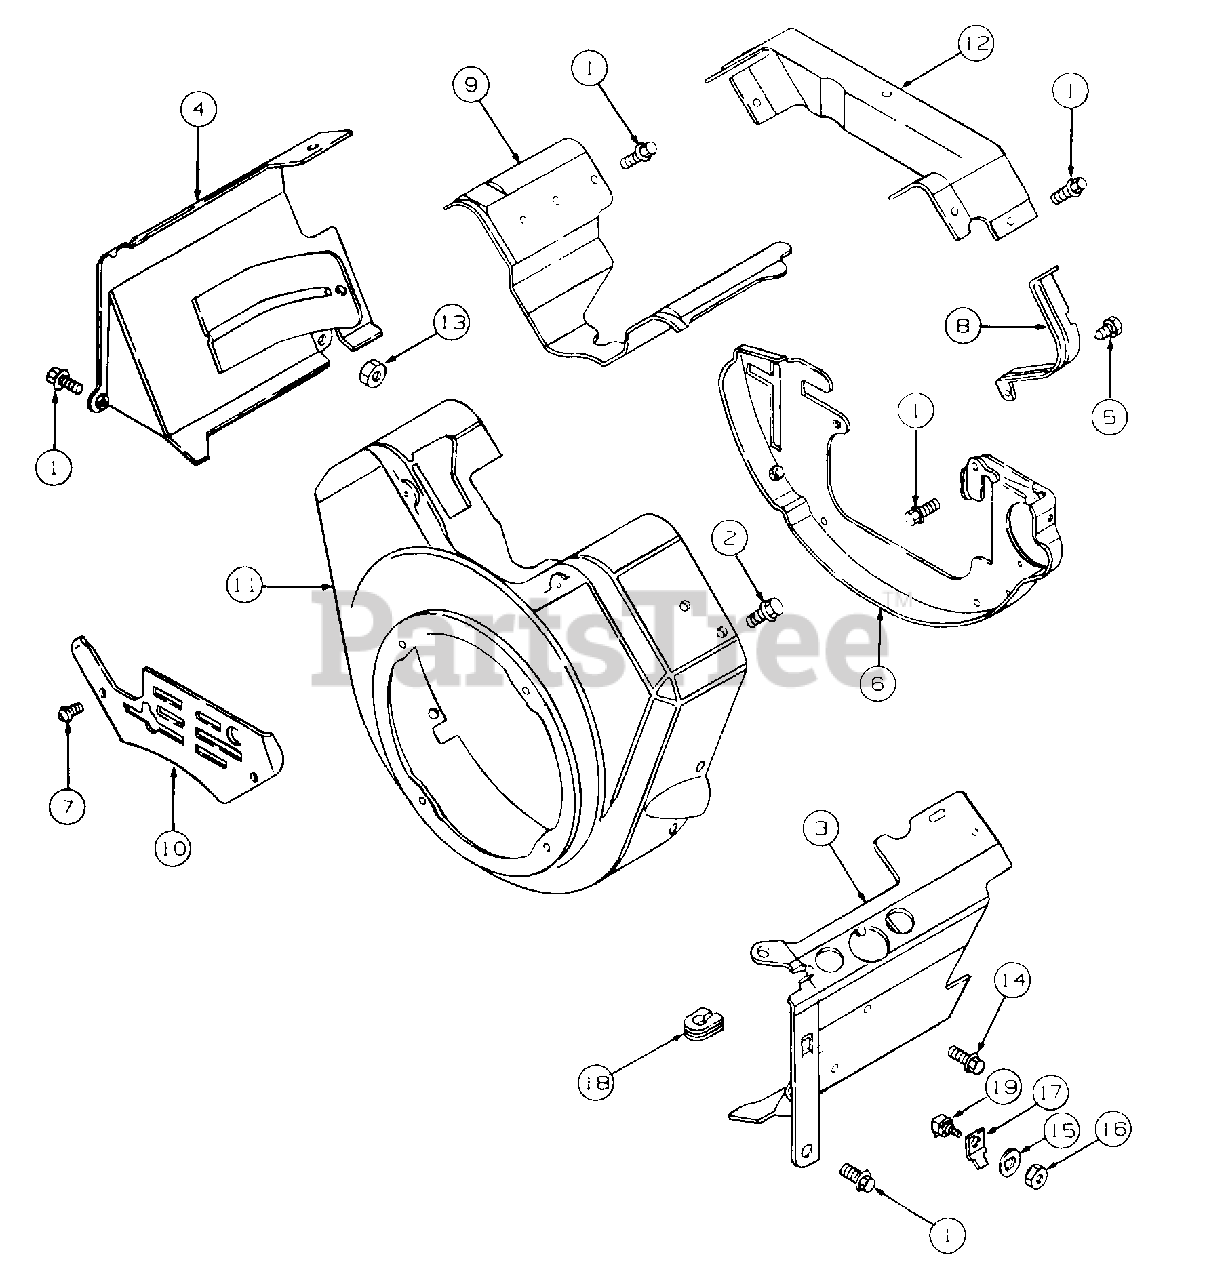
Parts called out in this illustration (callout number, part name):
1	Screw, Sems
2	Screw, Sems
3	Cover (Cylinder #1)
4	Cover (Cylinder #2)
5	Screw, Sems
6	Plate, Back
7	Screw, Sems
10	Cover, Carburetor
11	Housing, Blower
12	Cover, Valley Extension
13	Nut, Hex
14	Screw, Mtg
15	Washer, Lock, Internal Tooth
17	Terminal, Ground
18	Grommet, Cable
19	Insulator Assy
